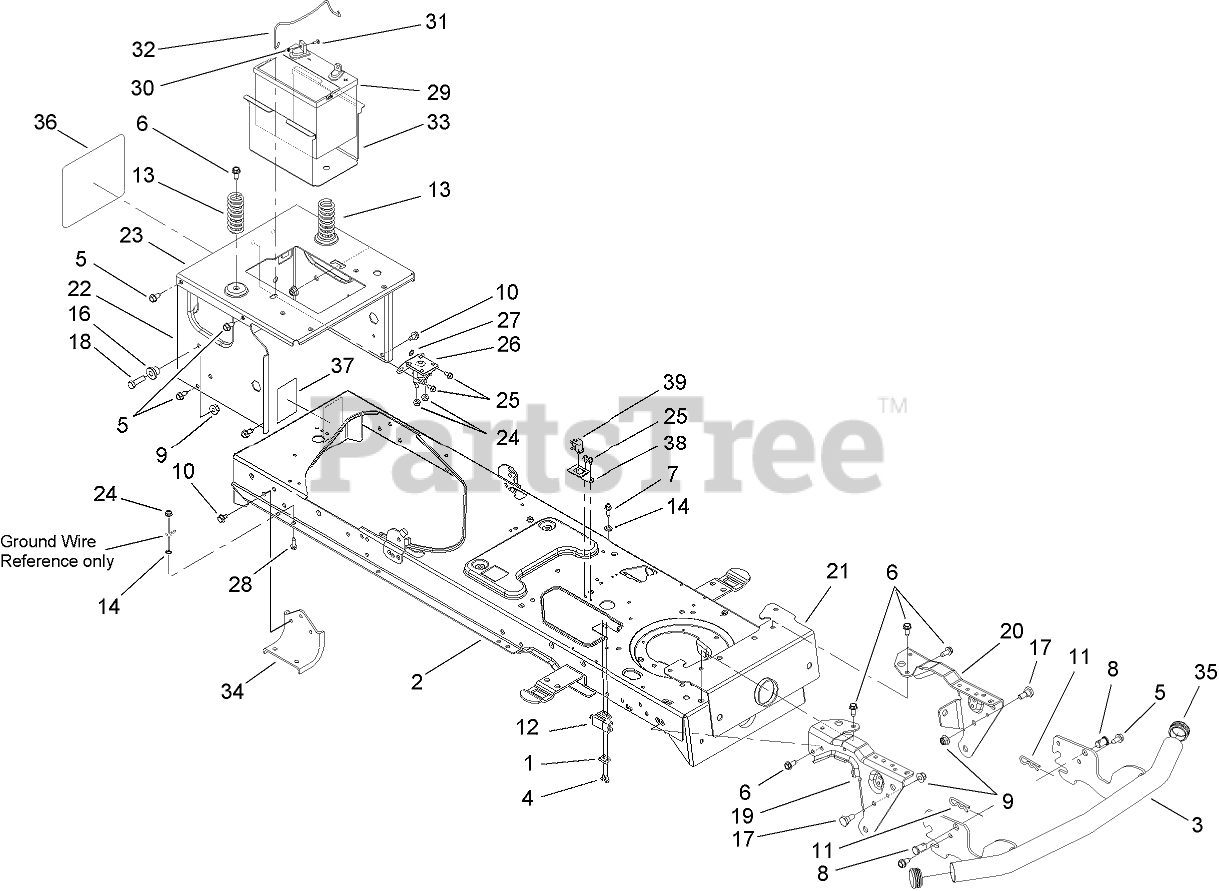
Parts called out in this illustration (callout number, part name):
1	PLATE-SWITCH
2	LOWER FRAME ASM
3	BUMPER ASM
4	SCREW-TAP
5	SCREW-HH, TAP
6	SCREW-HWH
7	SCREW-HWH
8	PIN-BRACKET, LIFT
9	NUT-LOCK, FLANGE
10	SCREW-TAP
11	PIN-HAIR
12	SWITCH-INTERLOCK
13	SPRING-COMPRESSION
14	WASHER-LOCK, EXTERNAL
16	SPACER-SHOULDER
17	BOLT-SHOULDER
18	SCREW-HH
19	BRACKET-PIVOT, SUPPORT
20	BRACKET-PIVOT, SUPPORT
21	BRACKET-PIVOT, BAR
22	FRAME-UPPER
23	BRACKET-FRAME, SEAT
24	NUT-LOCK, FLANGE
25	SCREW-HWHTF
26	SOLENOID-12V, 2 Post 1 Tab
27	WASHER-LOCK, EXTERNAL
28	SCREW-TAP
29	BATTERY-245, CCA (DRY FLAT TOP)
30	NUT-SEMS
31	BOLT-CARR
32	ROD-HOLDDOWN, BATTERY
33	TRAY-BATTERY
34	BRACKET-AXLE
35	BUMPER-CAP
36	DECAL-TORO
37	DECAL-BYPASS
38	BRACKET-SWITCH, PARKING BRAKE
39	SWITCH-MOUNT, SNAP
